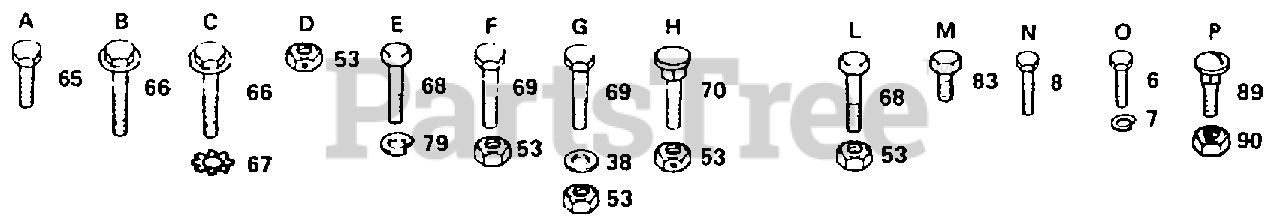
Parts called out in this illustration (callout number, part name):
6	BOLT
7	LOCKWASHER
38	WASHER
65	SCREW
66	SCREW LT
67	LOCKWASHER
69	BOLT
70	BOLT
79	LOCKWASHER
83	SCREW
89	BOLT
